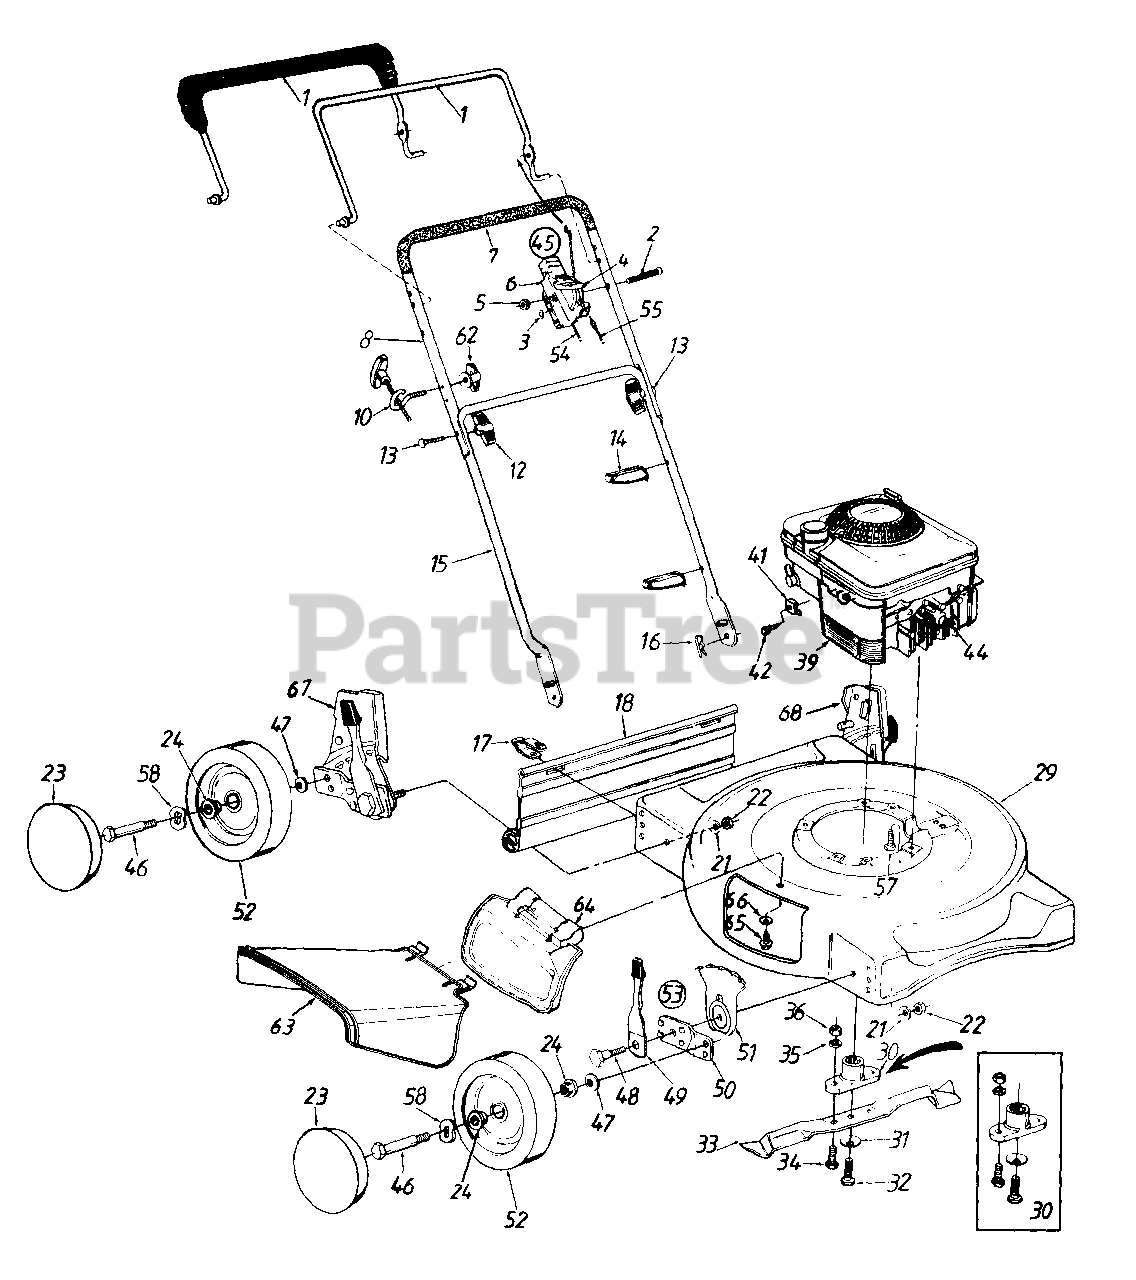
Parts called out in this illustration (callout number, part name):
1	Control Handle Ass'y.
2	Oval C-Sunk Scr.
3	Spr. Wash. .66" l.D.
4	Throttle Lever
5	Hex L-Nut 1/4-20 Thd.
6	Throttle Body
7	Grip
12	Hand Knob
13	Curved Hd. Bolt 5/16-18 x 2" Lg.
14	Cable Tie
16	Hairpin Cotter
17	Hinge Clip
18	Rear Flap
21	Bell-Wash..39" I.D. x 1.38"
22	Hex Nut 3/8-16 Thd.
23	Hub Cap
24	Bearing
29	20" Deck Ass'y.
30	Blade Adapter Kit
31	Bell-Wash..39" I.D.
32	Hex Bolt 3/8-24 x 1.5" Lg.
33	20" Mulching Blade
34	Hex Bolt 3/8-24 x 1" Lg.
35	L-Wash. 3/8" I.D.
36	Hex Nut 3/8-24 Thd.
39	Engine
41	Cable Clamp
42	Hex Self-Tap Scr. #10-32 x .62"
44	Spark Plug Boot
45	Throttle Box Comp.
46	Axle Bolt
47	Bell-Wash. .400" I.D. x .88"
48	Shld. Bolt .50" Dia. x .357"
49	Spring Lever Ass'y. w/Knob
51	Height Adj. Plate
52	Wheel Ass'y. Comp.
53	Height Adj. Ass'y. Comp.- R.F.
54	Throttle Cable - 51"
55	Control Cable - 39"
57	Hex L-Wash. Hd. Scr. 3/8-16 x 1.0" Lg.
58	Wave Washer .51" I.D.
62	Handle Knob 1/4-20 Thd.
63	Chute Deflector
64	Mulching Plug
65	Hex Wash. Hd. TT-Tap Scr. 1/4-20 x .5" Lg.
66	Bell-Wash. 1/4" I.D.
